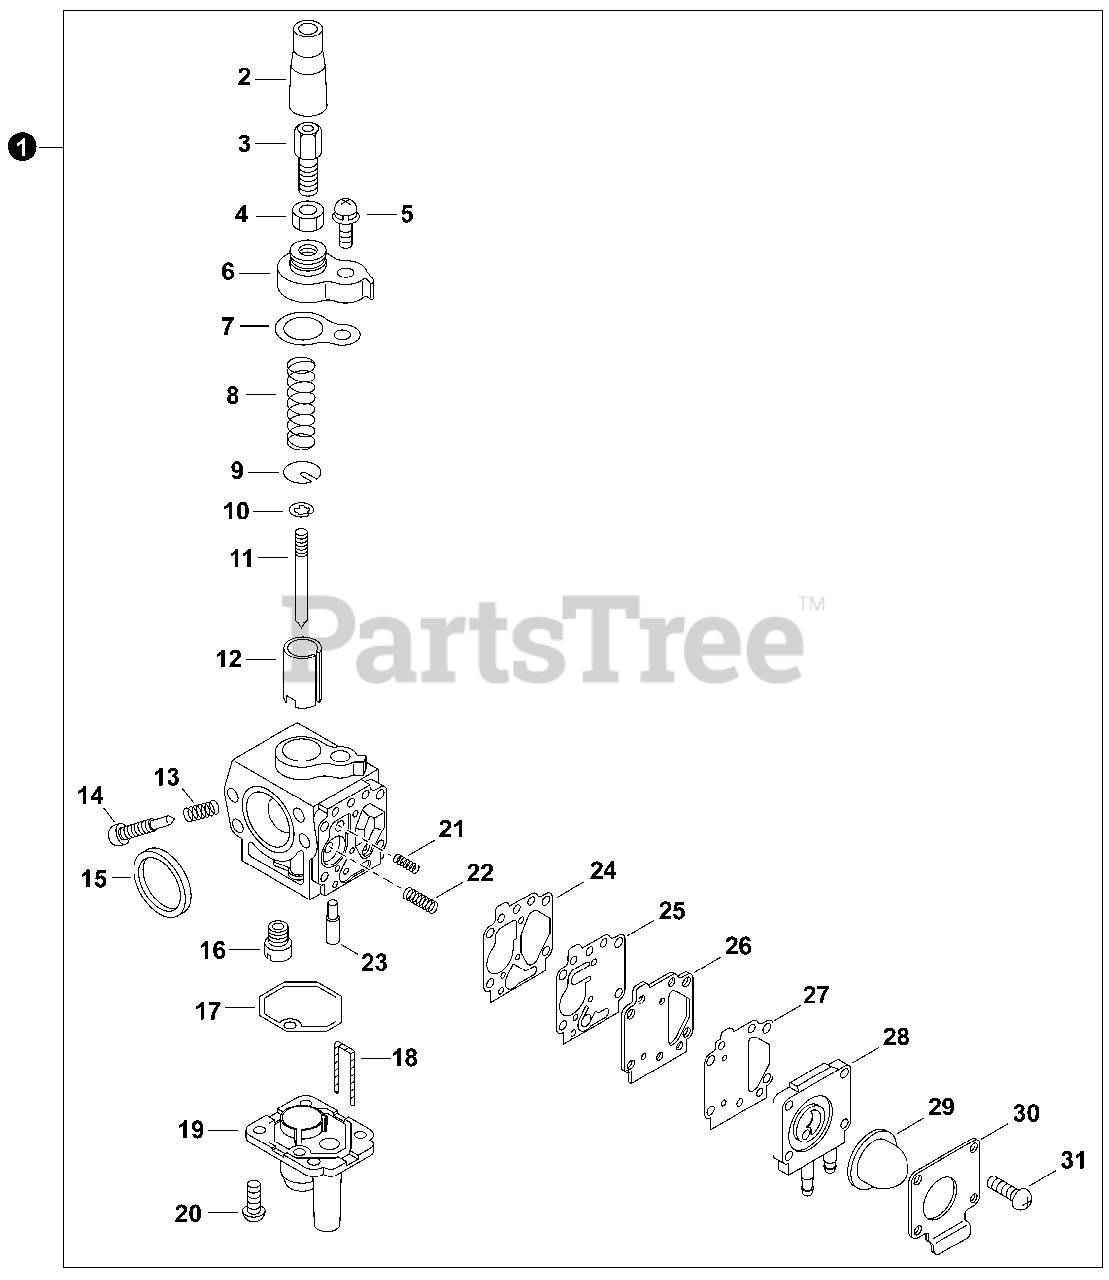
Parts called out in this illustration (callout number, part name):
1	CARBURETOR TK KR8PR-1B
2	CAP, RUBBER
3	ADJUSTER, CABLE
4	NUT, LOCK
5	SCREW 5x16
6	COVER, VALVE
8	SPRING, THROTTLE
9	WASHER, SPRING SUPPORT
11	NEEDLE, JET
12	VALVE, THROTTLE
14	SCREW, IDLE ADJUST
15	RING, PACKING
16	JET, MAIN #44
17	GASKET, CHAMBER
18	WIRE, DRAIN
19	CHAMBER, FLOAT
20	SCREW 3x10
23	NEEDLE, JET
24	GASKET, FUEL PUMP
25	DIAPHRAGM, FUEL PUMP
26	PLATE, FUEL PUMP
27	GASKET, FUEL PUMP
28	BODY ASSY, PUMP
29	BULB, PURGE
30	COVER, FUEL PUMP
31	SCREW 3x14
